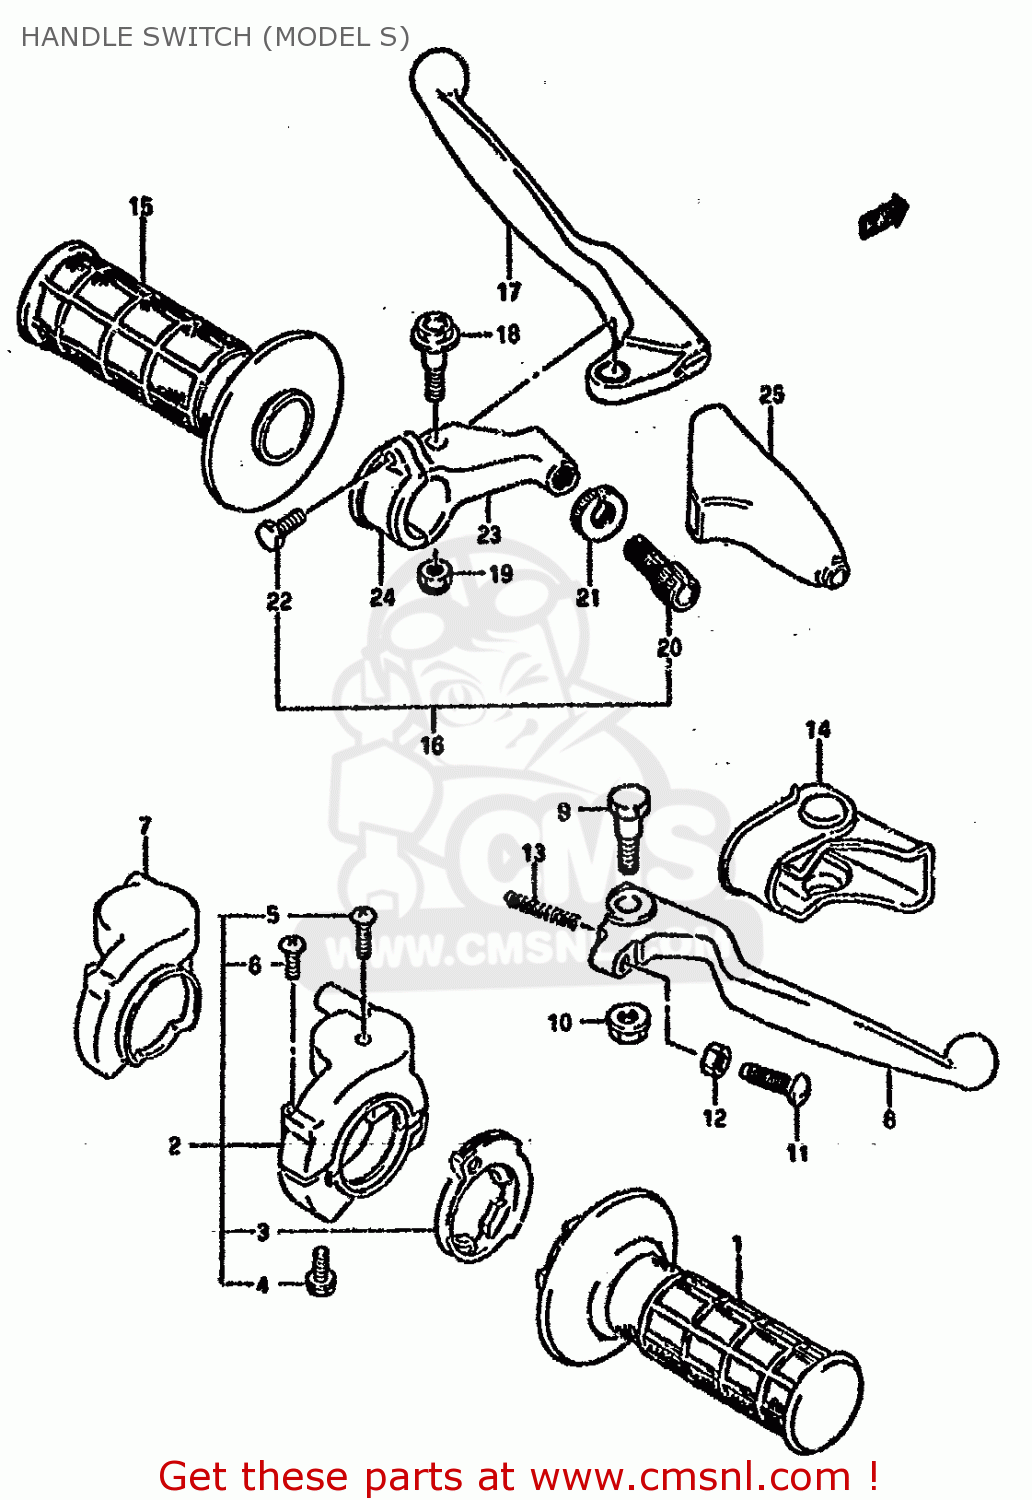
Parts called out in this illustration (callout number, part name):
1	GRIP,THROTTLE
2	CASE ASSEMBLY,THROTTLE
3	ROTOR,THROTTLE
4	BOLT 6X25
5	SCREW,UPPER
6	SCREW
7	COVER,THROTTLE CASE
8	LEVER,BRAKE
9	BOLT,BRAKE LEVER
10	NUT,BRAKE LEVER
11	BOLT,ADJUST
12	NUT ,5MM
13	SPRING,RETURN
14	COVER,BRAKE LEVER
15	GRIP,L
16	LEVER ASSEMBLY,CLUTCH
17	LEVER,CLUTCH
18	BOLT,LEVER
19	NUT 6MM
20	ADJUSTER,WIRE
21	NUT,LOCK
22	BOLT
23	HOLDER,CLUTCH LEVER
24	COVER,CLUTCH LEVER
25	COVER,CLUTCH LEVER
